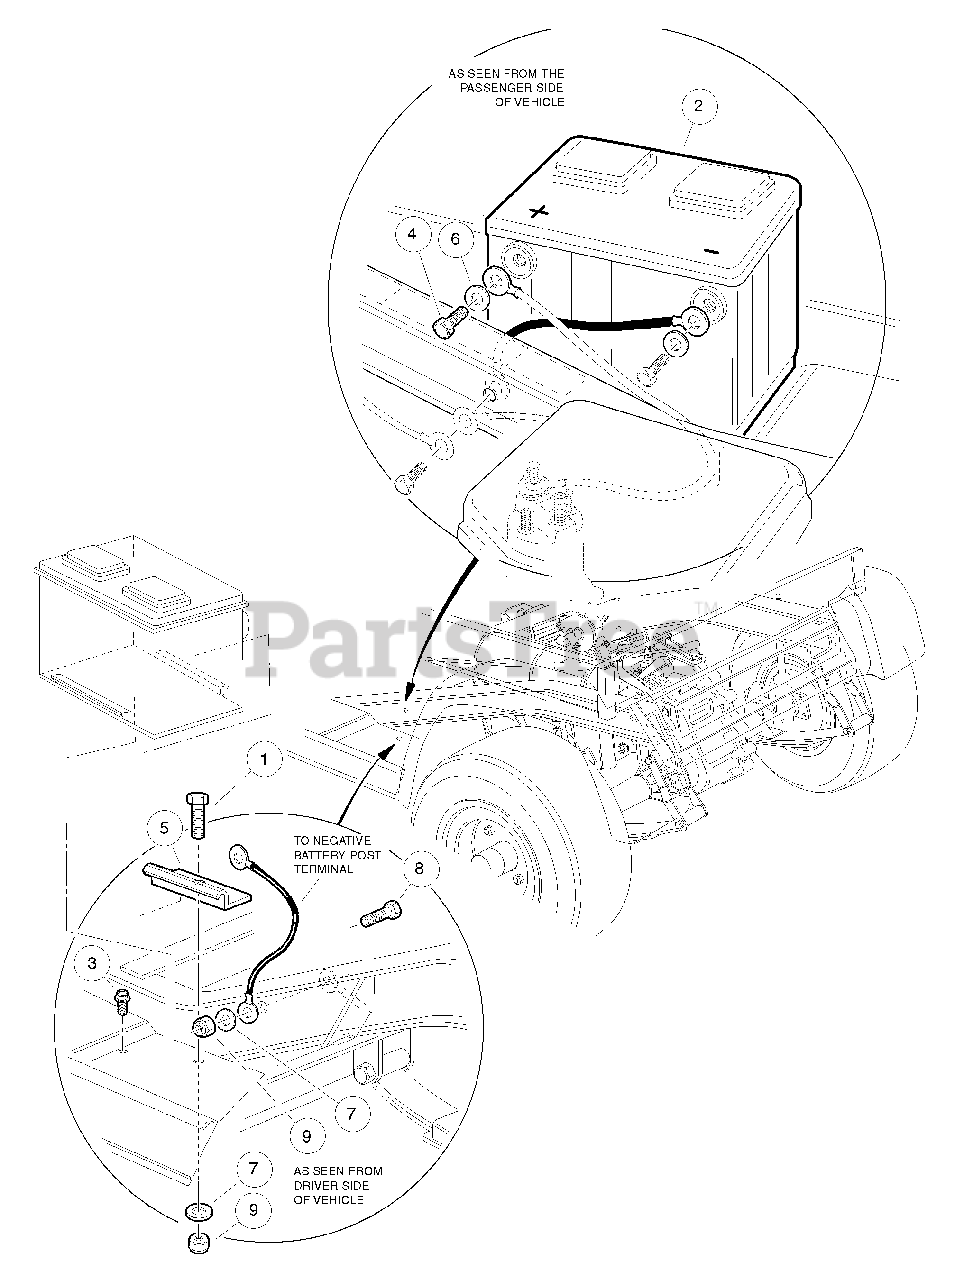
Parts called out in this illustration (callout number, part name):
1	Screw, 5/16-18 X 1.00 Hex Cap
2	Battery, 12-Volt
3	Screw, 5/16-18 X 0.75 Thread-Forming
4	Screw, 3/8-16 X 0.50 Stainless Steel Hex-Head
5	Clamp, Battery
6	Lockwasher, 3/8 Stainless Stl
7	Washer, 5/16 Type A Flat
8	Screw, 5/16-18 X 0.75 Hex-Head Cap
9	Locknut, 5/16-18 Nylon Insert
